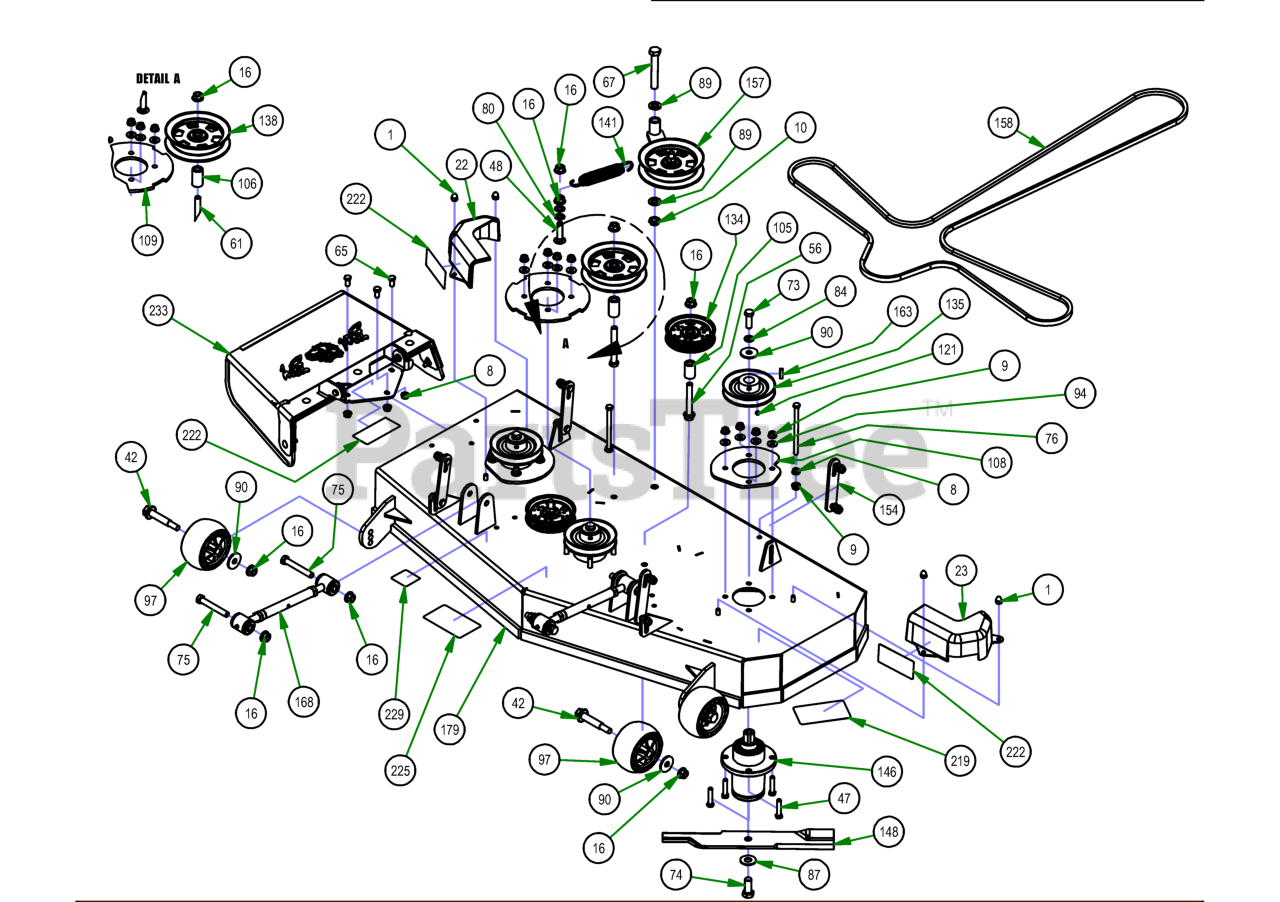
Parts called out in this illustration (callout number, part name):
1	5/16-18 ACORN NUT HIGH-CROWN ZC
8	3/8-16 HEX SERRATED FLANGE NUT HARD/ZINC
9	3/8-16 NYLON INSERT FLANGE LOCKNUT (GR.F) ZINC
10	5/8-11 NYLON INSERT JAM LOCKNUT ZINC
16	1/2-13 NYLON INSERT FLANGE LOCKNUT ZINC
22	pulley cover chute side
23	pulley cover non-chute side
42	Deck Wheel Bolt
47	3/8-16 X 1-3/4 HEX C/S (GR.5) ZC
48	1/2-13 X 2 CARRIAGE BOLT ZINC
56	1/2-13 X 3-1/2 HEX FLANGE BOLT (GR.8) ZINC
61	1/2-13 X 4 HEX CAP SCREW (GR.8) ZINC YELLOW
65	3/8-16 X 3/4 HEX CAP SCREW (GR.5) ZINC
67	5/8-11 X 4 HEX CAP SCREW (GR.8) ZINC YELLOW
73	1/2-20 X 1-1/2 HEX CAP SCREW (GR.5) ZINC
74	5/8-18 X 1-1/2 HEX CAP SCREW (GR.8) ZINC YELLOW
75	1/2-13 X 3-1/2 HEX CAP SCREW (GR.5) ZINC
76	3/8-16 X 5-1/2 HEX CAP SCREW (GR.5) ZINC
80	.517 SQ WDTH ID X .937 OD X .060 THICK F/W PHOS/OIL
84	1/2 SPLIT LOCKWASHER (GR.8) ZINC/YELLOW
87	5/8 USS FLAT WASHER (1-3/4" OD) GR.8 ZINC YELLOW
89	.635 ID X 1.120 OD X .140 THICK FLAT WASHER NYLON
90	1/2 BELLEVILLE WASHER (1-5/8 OD X .140 THK) ZINC
94	5/16 USS FLAT WASHER (7/8 OD) ZINC
97	Deck Wheel
105	.502 ID X .750 OD X 1.500 Long Spacer
106	1 3/4" Pulley Spacer
108	42&48 Deck Spindle Support Plate
109	Deck Spindle Support Plate
121	5/16-24 X 1/4 SOCKET SET SCREW (CUP PT) PLAIN
134	4 3/4 Idler Pulley - ABFI-76
135	5" Spindle Deck Pulley
138	5-3/4 Idler Pulley
141	Deck Idler Spring
146	Spindle Assembly
148	48" ZT/Mav/Compact Outlaw Blade with Fusion
154	Deck Hanger Assembly
157	2017 54"/48" Deck Idler Assembly
158	B147 Deck Belt
163	1/4 X 1 SQ MACHINERY KEY 1018 STL PLN
168	2018 Maverick Turnbuckle (Top Link)
179	2017 48" ZT Deck Welded Assembly
219	2018 48" Deck Decal
222	Danger Decal-Spindle/Discharge
225	Deck Belt Route Decal
229	Deck Impact Patent Decal 9591803
233	ZT Chute Assembly
